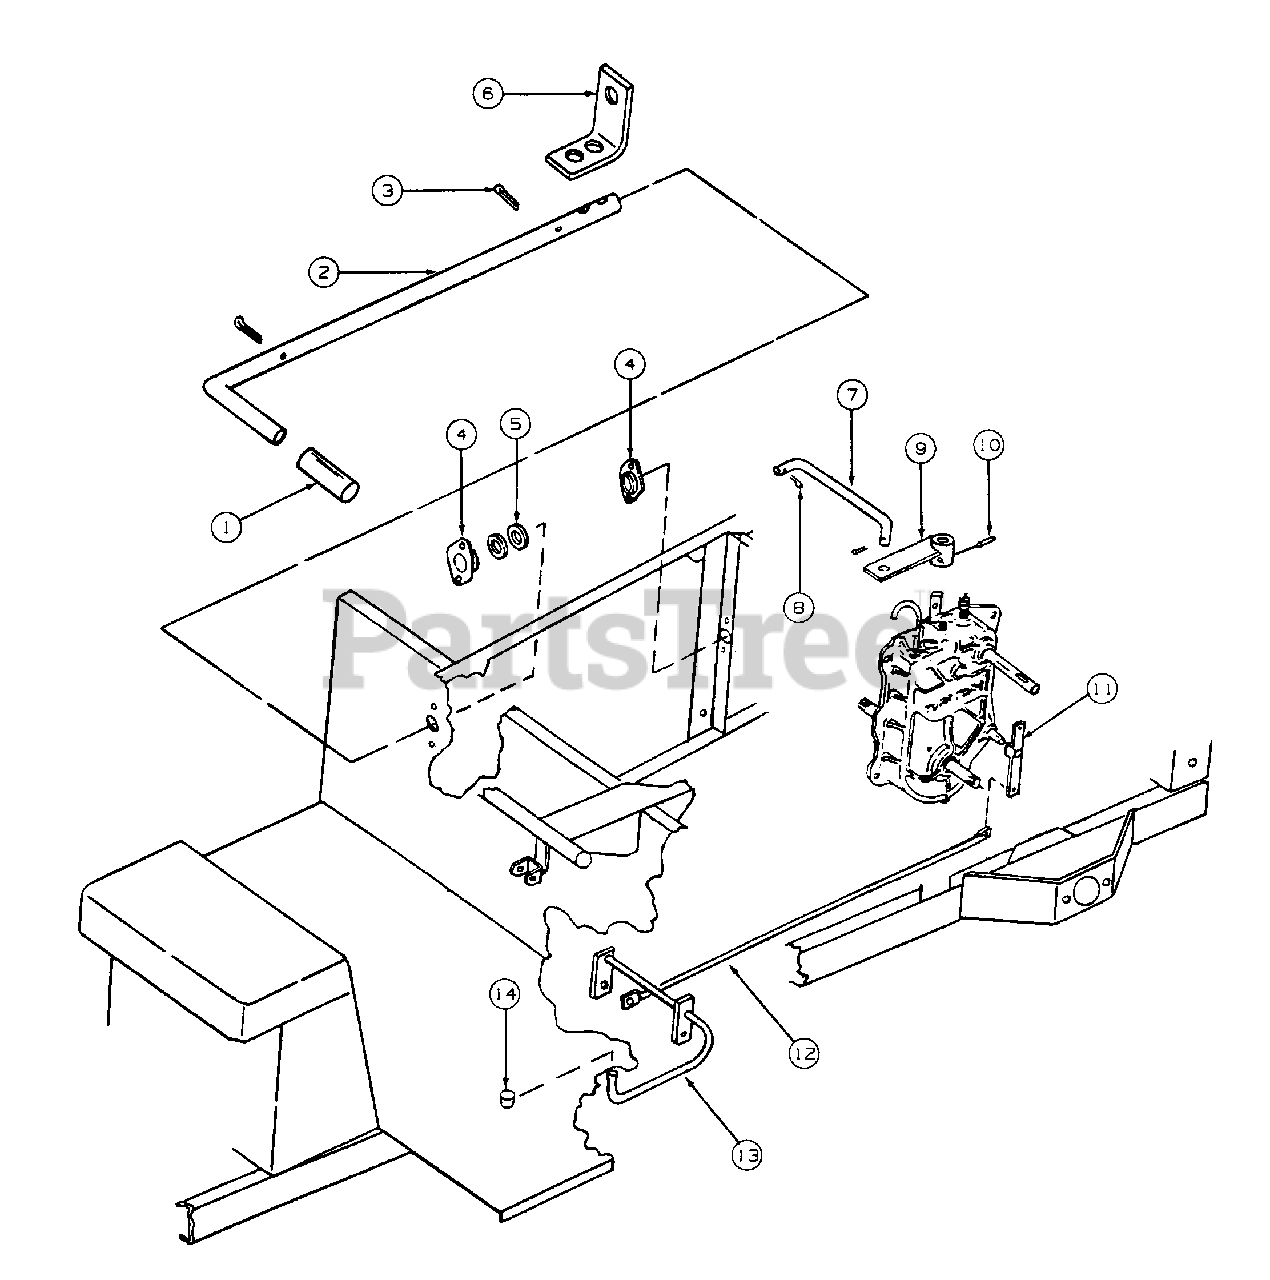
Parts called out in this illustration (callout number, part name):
1	Grip (3/4" Bar)
2	Tube, Shift
3	Pin, Cotter, .19 X 1.5
4	Bearing, Flange, .75 ID
6	Bracket, Shift
7	Rod, Shift
8	Pin, Cotter, .13 X .5
9	Arm, Shift Actuator
10	Pin, Roll, .25 X 1.5 HBK
11	Arm, Diff Lock
12	Rod, Diff Lock
13	Pedal, Diff Lock Control
14	Tip, Molded, .5"
